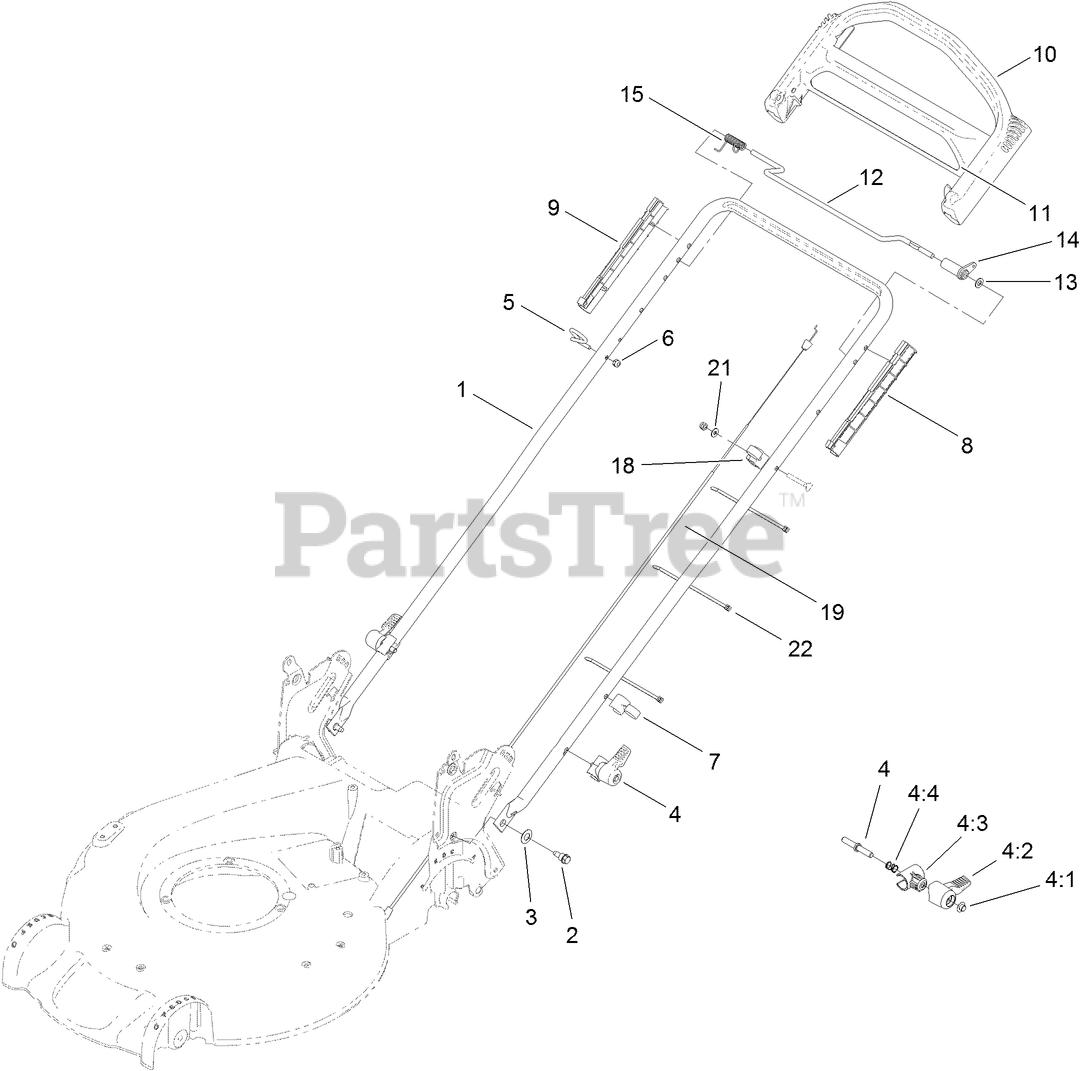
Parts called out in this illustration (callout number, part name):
2	BOLT-SHOULDER
3	WASHER-SPRING, CONICAL
4	QUICK RELEASE ASM
4:2	LEVER
4:3	ANCHOR-SPRING
4:4	SPRING-COMPRESSION
5	GUIDE-ROPE
6	NUT-LOCK, NI
7	GUIDE-CABLE
8	GUIDE-LH
9	GUIDE-RH
10	HANDLE-CONTROL
13	WASHER-PLAIN
14	LEVER-TRACTION
19	CABLE-TRACTION
21	WASHER-FLAT
22	TIE-CABLE
